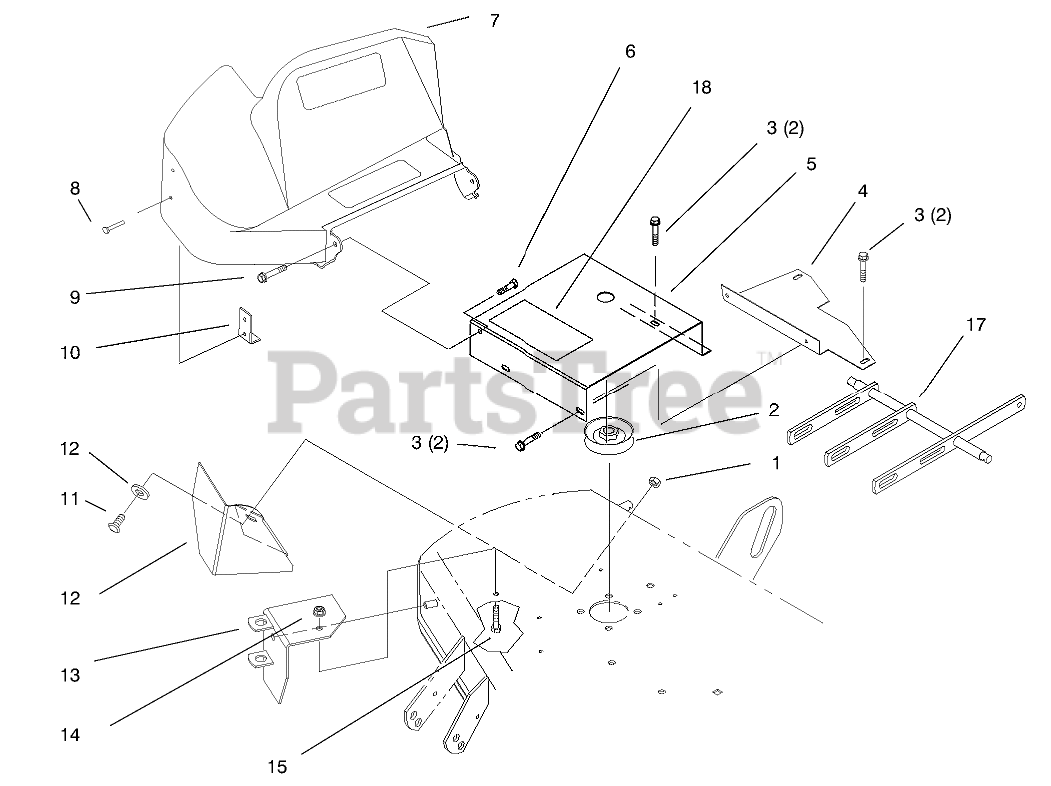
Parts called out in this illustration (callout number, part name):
1	NUT-LOCK, NI
2	PULLEY
3	SCREW-HWH
4	42" ADAPTOR SHIELD B
5	Inner Shield Asm. (Incl. Ref. #18)
6	SCREW-HH
7	SHIELD-BELT
8	RIVET-POP
9	NUT-LOCK, NI
10	BRACKET-SUPPORT, SHIELD
11	SCREW-HH
12	42" DEFLECTOR B
13	PIVOT SUPPORT ASM
14	NUT-HF
15	SCREW-HH
16	WASHER-FLAT
17	Bar-Leveler
18	DECAL-DANGER
